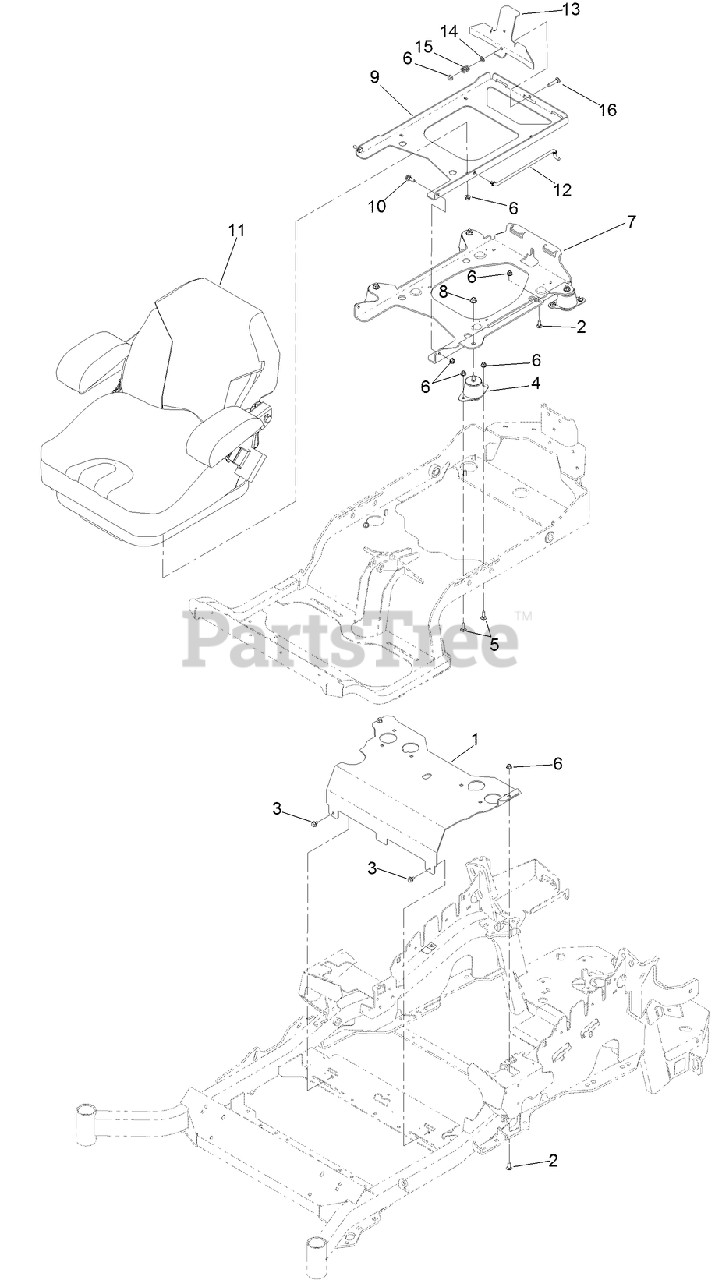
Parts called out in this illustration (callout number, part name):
1	PANEL-FRONT, SEAT MOUNT
2	SCREW-CARR
3	SCREW
4	ISOLATOR-SEAT
5	BOLT-CARR
6	NUT-HF, NI
7	PLATE-SUPPORT, ISO SEAT
8	NUT-HF, NI
9	PLATE-FRAME, SEAT
10	SCREW-SHOULDER
11	SEAT-STANDARD
12	ROD-PROP
13	PLATE-LATCH,SEAT
14	WASHER-PLAIN
15	SPRING-COMPRESSION
16	BOLT-CARR
